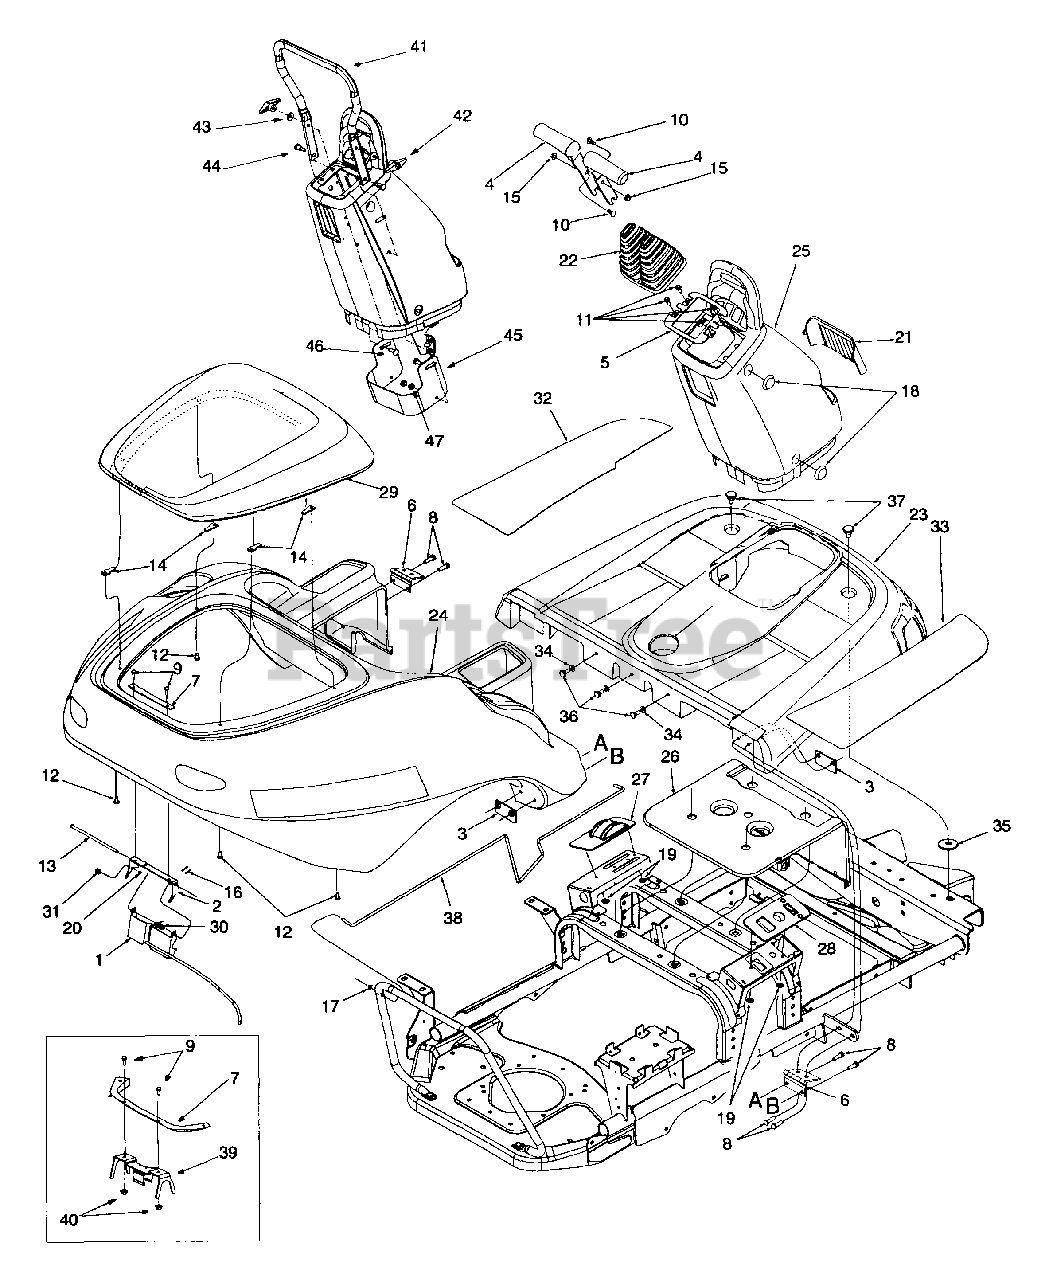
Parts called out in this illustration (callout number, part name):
1	Handle Ass'y, Latch
4	Handle, Control
7	Plate, Latch Mounting
8	Screw, Hex Cap, 5/16-18 x 1.0 GR5
9	Screw, Pan Hd, #10-24 x .625
10	Bolt, Carriage, 5/16-18 x .75
11	Screw, Hex Wash. Hd. Tap 1/4-20 x .75
12	Screw, Truss Machine 1/4-20 x .625 GR2
13	Rod, Latch Mounting
14	Nut, U-Type Speed, 1/4-20
15	Nut, Hex Flange Lock, 5/16-18 GR5
16	Pin, Cotter, 1/16 x .75
17	Push Cap, 1/4
18	Plug, Button
19	Push Nut
20	Rivet, Pop, .125 Dia
21	Lens, Headlight
22	Bellow, Control
23	Body, Front Floor
24	Body, Rear Engine Compartment
26	Cover, Seat Base
27	Cover, LH Control Panel
28	Cover, RH Control Panel
29	Cover, Engine
30	Spring, Torsion
31	Clip, Spring
32	Pad, Floor LH
33	Pad, Floor RH
34	Washer, Flat
35	Washer, Flat, .406 x 1.5 x .110
36	Bolt, Shoulder
37	Bolt, Shoulder, .75 x .245:3/8-16
38	Rod, Prop Support
39	Clip Spring Bracket Assembly
40	Hex Nut Lock Flange 1/4-20
43	Bell Wash .340 ID
44	Shoulder Screw .437 Dia .54
47	Nut, Hex Flange Lock, 5/16-18 GR5
